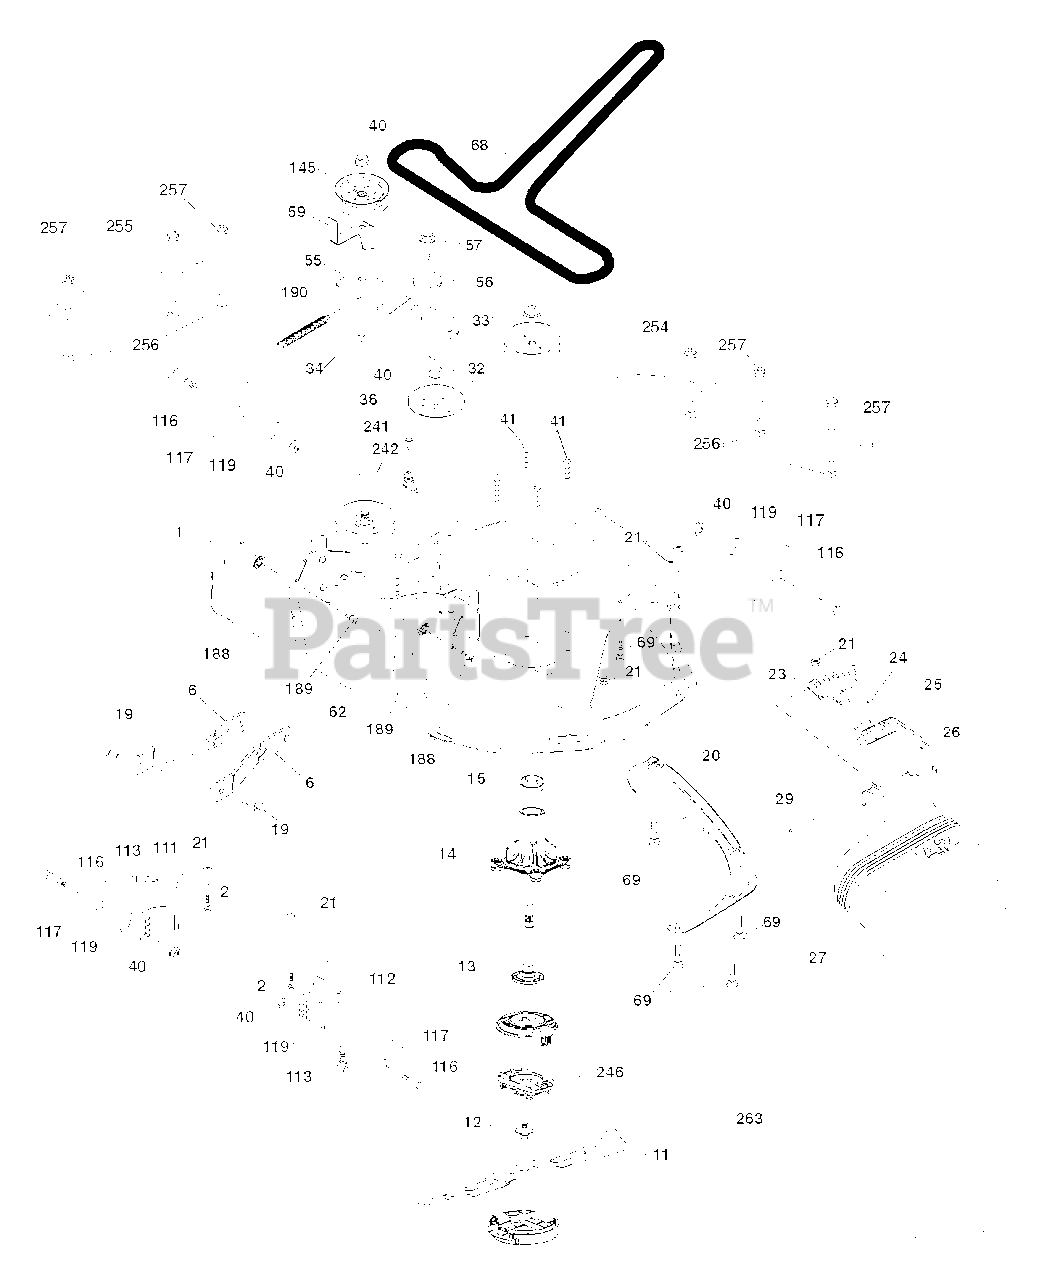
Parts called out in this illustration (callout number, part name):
1	DECK.SVC.42"2GW
2	BOLT 5/16-18 X3/4 ZN/YEL GR 5
6	ARM.SUSPENSION.MOWER.R
11	BLADE.REVOLUTION.42"3IN1.PT43
12	SCREW.SEMS.7/16-20X1.HEX.HEAD
13	SHAFT ASM.REV.TALL.N/GREASEBL
14	HOUSING.MANDREL.REV.TALL.N/GRS
15	BEARING.MANDREL.TOP.EXTENDED
19	BOLT.SHOULDER
20	BAFFLE.VORTEX
21	LOCKNUT
23	BRKT.DEFLECTOR.38"2005+
24	CAP-SLEEVE LT
25	SPRING.TORSION.DEFLECT
26	NUT PUSH M
27	SHIELD.DEFLECTOR.MOWER.42"BLAC
29	ROD.HINGE
32	PULLEY/MANDREL
33	NUT.FLANGE.LOCK.TOP
34	BOLT.3/8-16X1.50
36	PULLEY.IDLER.2006
40	NUT LOCK FLG 3/8-16 UNC
41	BOLT.HEX.WASHR.HED.313-18X1.19
55	IDLER.ARM.42"
56	SPACER.RETAINER
57	SCREW 3/8-16X1
59	GUARD, BELT
68	BELT V SECONDARY
69	BOLT
111	BRKT.WHEEL.GAUGE.LH.42"
112	BRKT.WHEEL.GAUGE.RH.42"
113	BOLT.5/16HEX.WHS.HD
116	BOLT M
117	WHEEL.GAGE.HALF.SPOKED
119	WASHER
145	PULLEY.IDLER.48"PRIMARY
188	STUD.FASTNER.W/ANTI-ROTATE
189	NUT LOCK HEX FLANGE 5/16-18
190	SPRING.MOWER.DRIVE.ELECTRIC
241	SCREW.TT.#10-32X.5.3/8.FLANGE
242	PORT.WASHOUT
246	HOLDER.BLADE.REVOLUTION
254	PLATES.RENFRC.42DECK.PT431FRNT
255	PLATES.RENFRCE.42DECK.X431SIDE
256	RHSNB, 1/4-20 X 1, GR5
257	NUT T
263	CAP.REVOLUTION ASM
